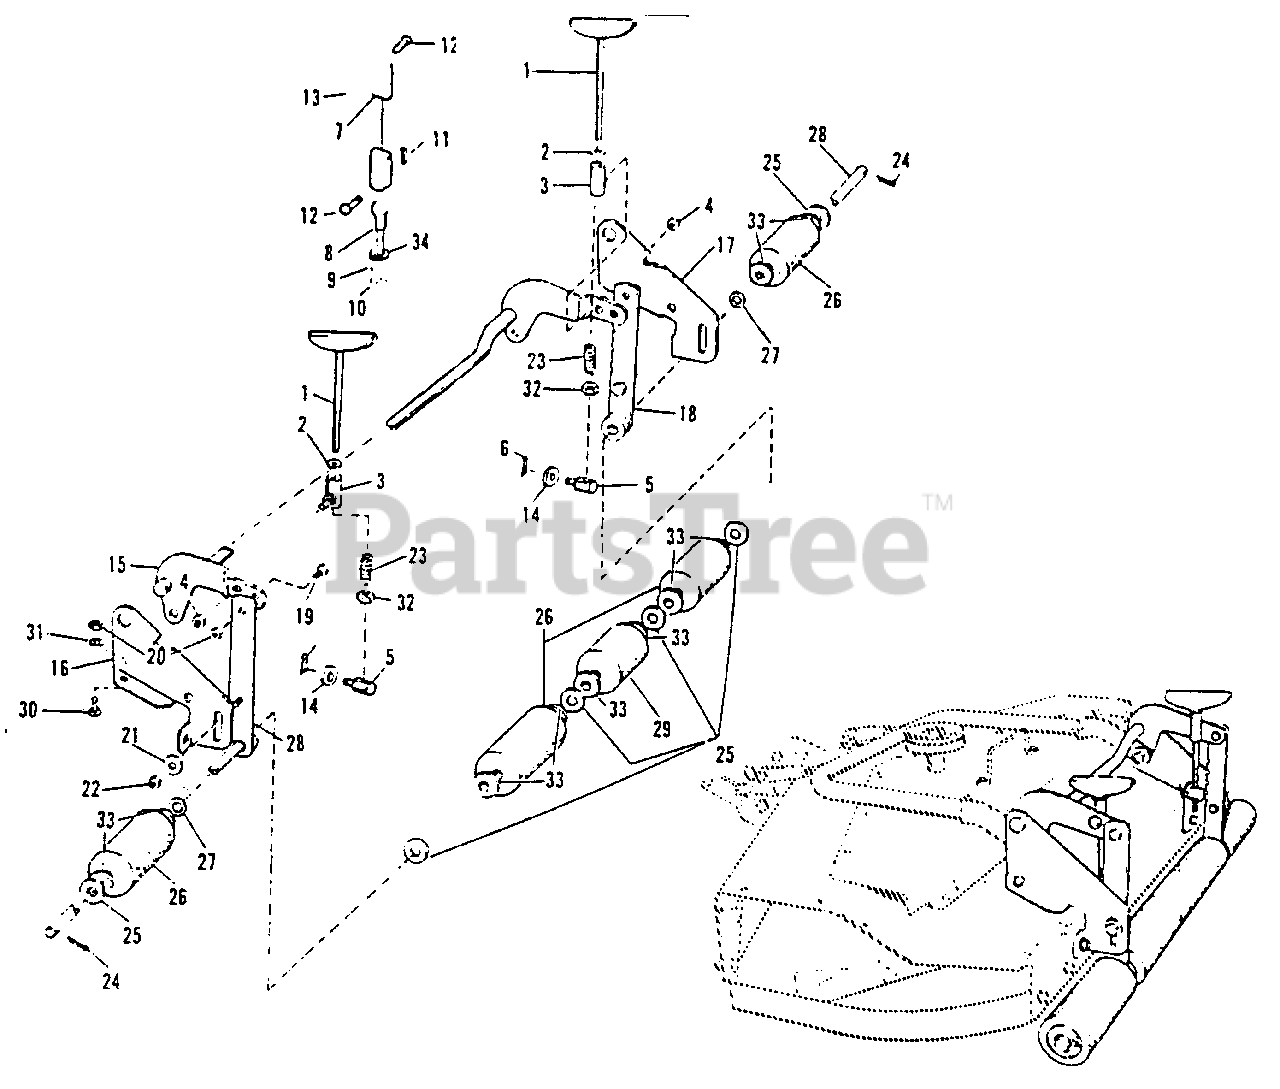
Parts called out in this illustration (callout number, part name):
1	Screw Assembly, Adjusting
2	Washer, Plain, 3/8"
3	Socket Assembly, Crank
4	Nut, Hex. Full, Lock, 3/8" 16 NC
6	Cotter Pin, 3/32" x 3/4" Lg.
7	Cable Assembly, Lift
9	Lock Washer, 3/8" Std.
10	Nut, Hex., Full, 3/8-16 NC
11	Pin, Cotter 3/32" x 3/4"
13	Clip, Spring
14	Washer, Plain. 3/8" Std
15	Arm. Assembly, Rocker
16	Bracket, Roller, R.H.
17	Bracket, Roller, L.H.
18	Bar Assembly, Roller
19	Capscrew, Hex. Hd., 3/8"-16 NC x 1" lg.
20	Nut, Hex., Full, 3/8"-16 NC
21	Washer, Plain, 3/8"
22	Nut, Hex., Full, Lock, 3/8"-16 NC
23	Spring, Adj. Screw
24	Pin, Cotter, 3/16" x 1" lg.
26	Roller W/Bushing
28	Shaft & Support Arm.
29	Roller W/Bushing
30	Bolt, Carriage, 3/8"-16 NC x 3/4" lg.
31	Washer Lock, 3/8"
32	Nut, Hex., Full 3/8"-16 NC
34	Plain Washer
